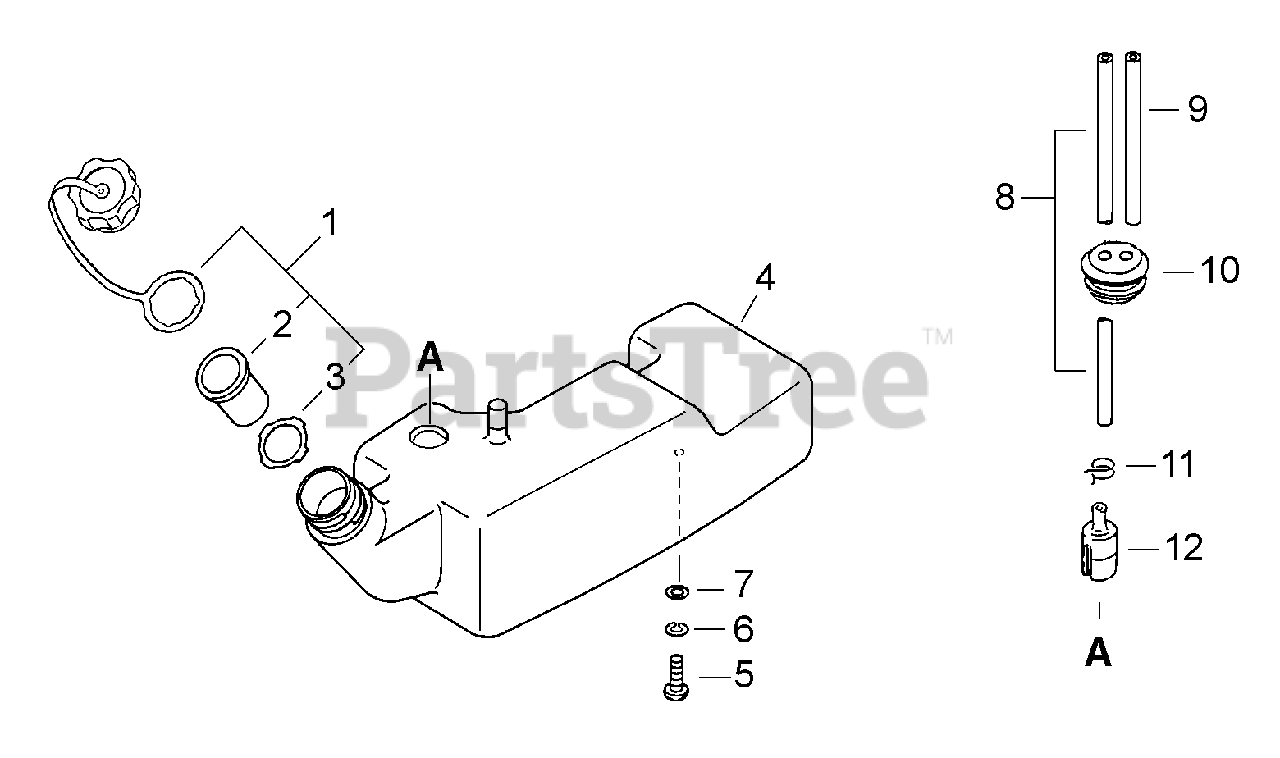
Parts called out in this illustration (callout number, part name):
1	CAP ASSY
2	VENT, CAP
3	GASKET, CAP
4	TANK, FUEL
5	SCREW - 6X14
6	LOCKWASHER - 6
7	WASHER - 6.5
8	PIPE - 3X6X280 -- BLACK
9	PIPE - 3X6X145 -- CLEAR
11	CLIP - 6.5
12	FILTER, FUEL
